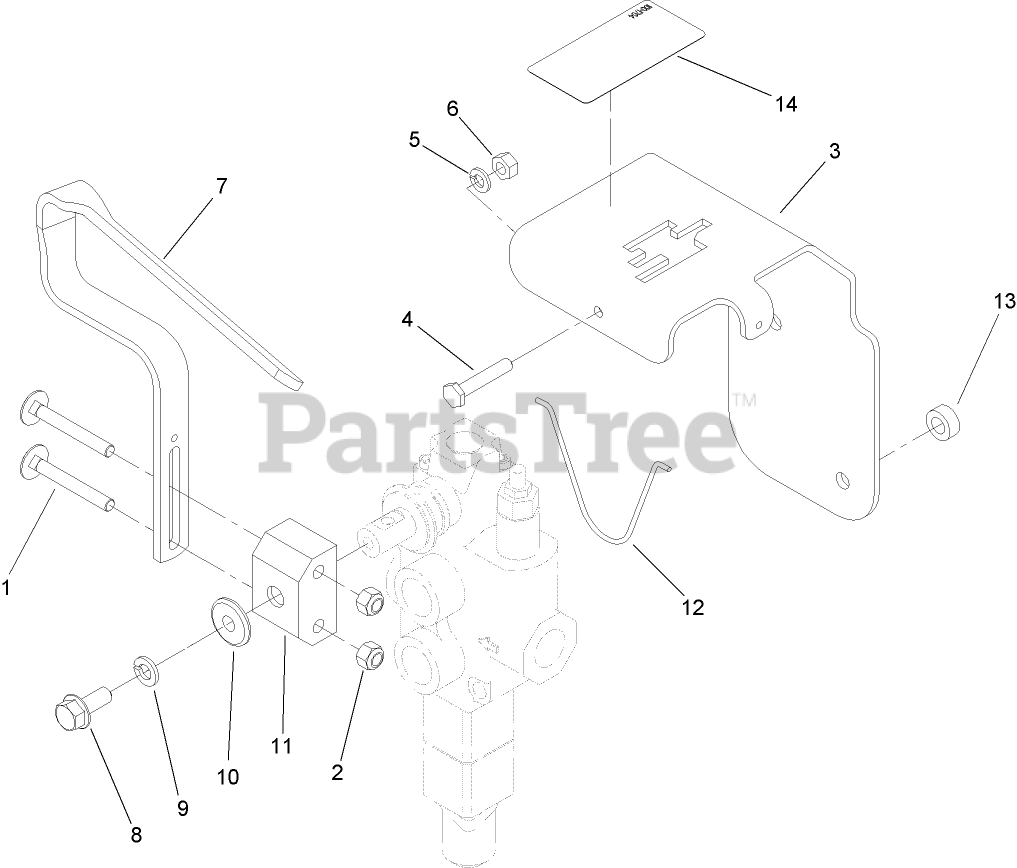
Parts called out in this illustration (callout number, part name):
1	SCREW-CARR
2	NUT-LOCK, NI
3	BRACKET
4	SCREW-HH
5	WASHER-LOCK
6	NUT-HEX
7	GRIP-CONTROL
8	SCREW-HHF
9	WASHER-LOCK
10	CAP-MOUNT
11	MOUNT-LEVER
12	SPRING-TORSION
13	SPACER
14	DECAL-POWER, AUXILIARY
